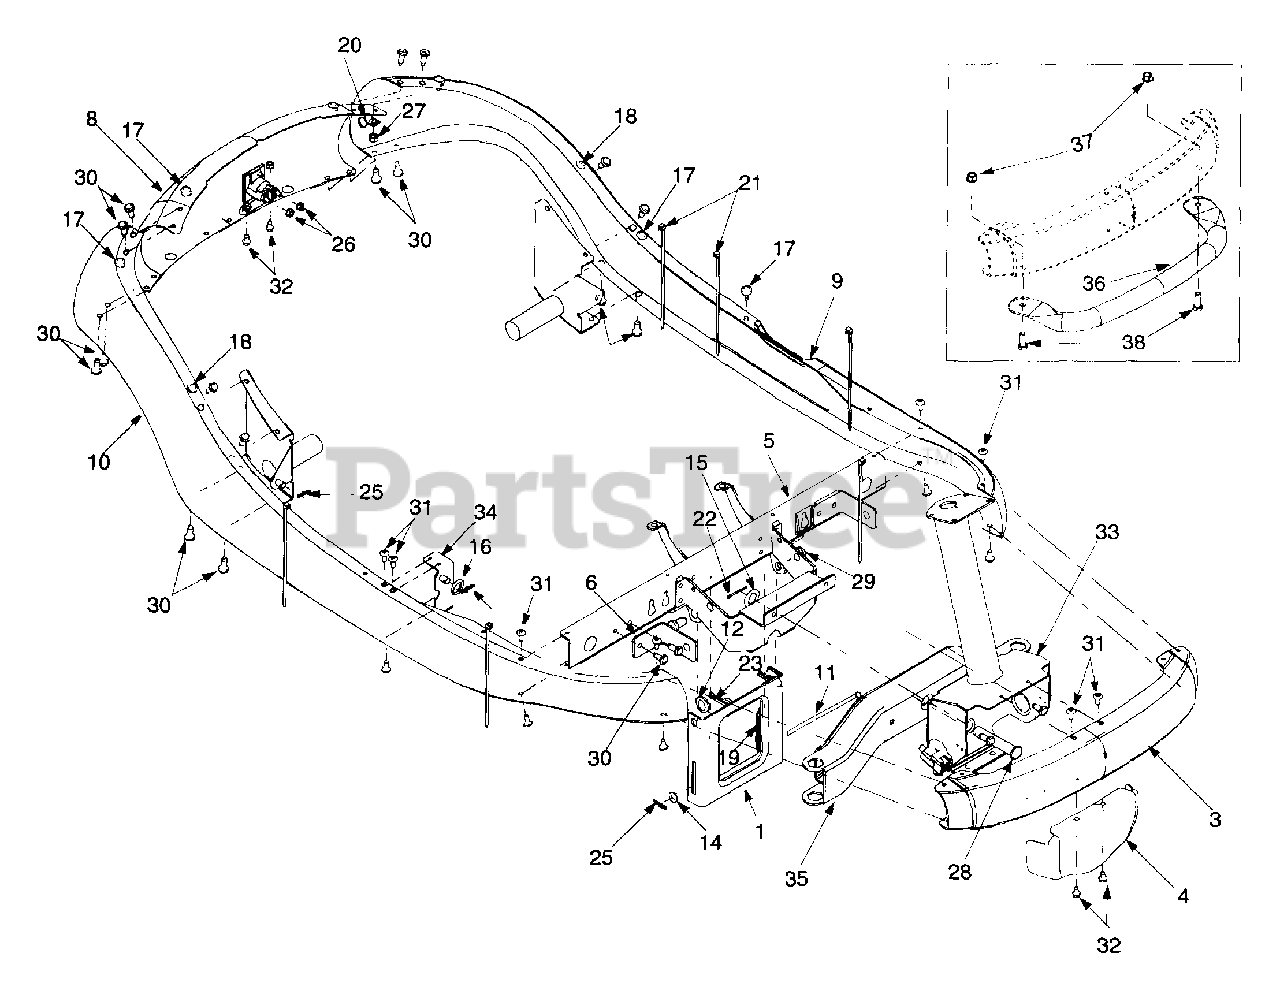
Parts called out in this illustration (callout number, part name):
12	Flat Washer .531 X 1.062 X .134
14	Flat Washer 5/16
15	Flat Washer .64 I.D. X 1.24 X.06
16	Flat Washer 3/8 X 1.00 X .030
17	Rubber Bumper
18	Rubber Bumper
19	Extension Spring
20	Clamp: 9/16 dia.
21	Cable Tie
22	Hairpin Clip
23	Hairpin Clip
25	Hairpin Clip
26	Hex Nut
27	Hex Nut 1/4-20
28	Clevis Pin
29	Lift Bracket Pin
30	TT Screw 5/16-18 x .75
31	Torx Mph. AB Scr. 1/4-14 x 0.625"
32	Hex TT Screw 1/4-20
37	Lock Nut 3/8-16
38	Hex Bolt 3/8-16 x 1.0" Gr. 5
